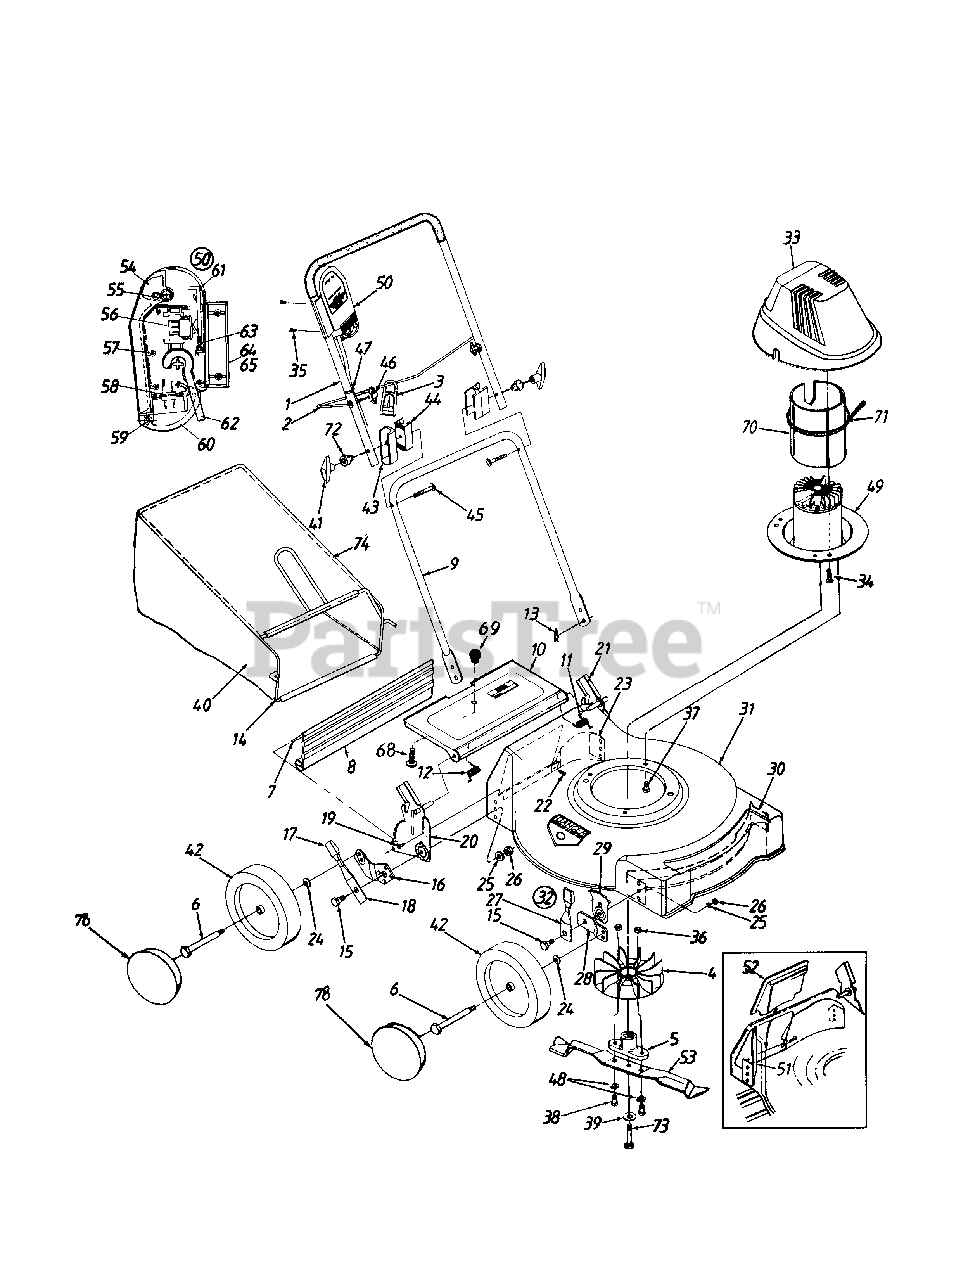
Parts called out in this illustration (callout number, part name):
3	Strain Relief--Cord
5	Blade Adapter
6	Axle Bolt
7	Rear Flap Wire
8	Rear Flap
9	Lower Handle
12	Door Spring--R.H.
13	Hairpin Clip
16	Pivot Bar--R.H.
17	Spring Lever Knob
18	Spring Lever
19	Hex L-Wash. Hd. AB-Tap Scr. 1/4 x .62" Lg.
20	Handle Brkt. Ass'y.--R.H.
21	Handle Brkt. Ass'y.--L.H.
22	Torx. Mach. AB-Tap Scr. 1/4 x .62" Lg.
23	Rear Baffle
24	Bell-Wash. .38" I.D. x .88" O.D.
25	Bell-Wash. .39" I.D. x 1.38" O.D.
26	Hex Nut 3/8-16 Thd.
27	Spring Lever Ass'y. w/Knob
29	Height Adj. Plate
33	Motor Cover
34	Scr. #10-16 x .75" Lg.
35	Self-Tap. Scr. #7 x 1" Lg.
36	Hex Nut 3/8-24 Thd.
37	Hex L-Wash. TT-Tap Scr. 3/8-16 x .75" Lg.
38	Hex Bolt 3/8-24 x 1.25" Lg.
39	Bell-Wash. .396" I.D. x 1.14"
40	Grass Bag
41	Plastic Knob
42	Wheel Ass'y. Comp.
43	Upper Handle Insulator
44	Lower Handle Insulator
45	Carriage Bolt 5/16-18 x 3" Lg.
46	Wing Nut 1/4-20 Thd.
47	Cable Tie
48	Bell-Wash. 3/8" I.D.
49	Motor, Cord & Switch Ass'y.
50	Cord & Switch Ass'y. Comp.
53	19" Mulching Blade
54	Handle--Switch Actuator
55	Spring--Switch Handle
56	Switch
57	Screw #6-32 x .5" Lg.
58	Plug Ass'y.
59	Retainer Plug Spring
60	Retainer Plug
62	Cord Ass'y.
63	Spring Latch
64	Housing--Upper Half
68	Truss Scr. #10-24 x .38" Lg.
70	Insulator
71	Cable Tie
72	Insulator Knob
73	Hex Bolt 3/8-24 x 2.5" Lg.
